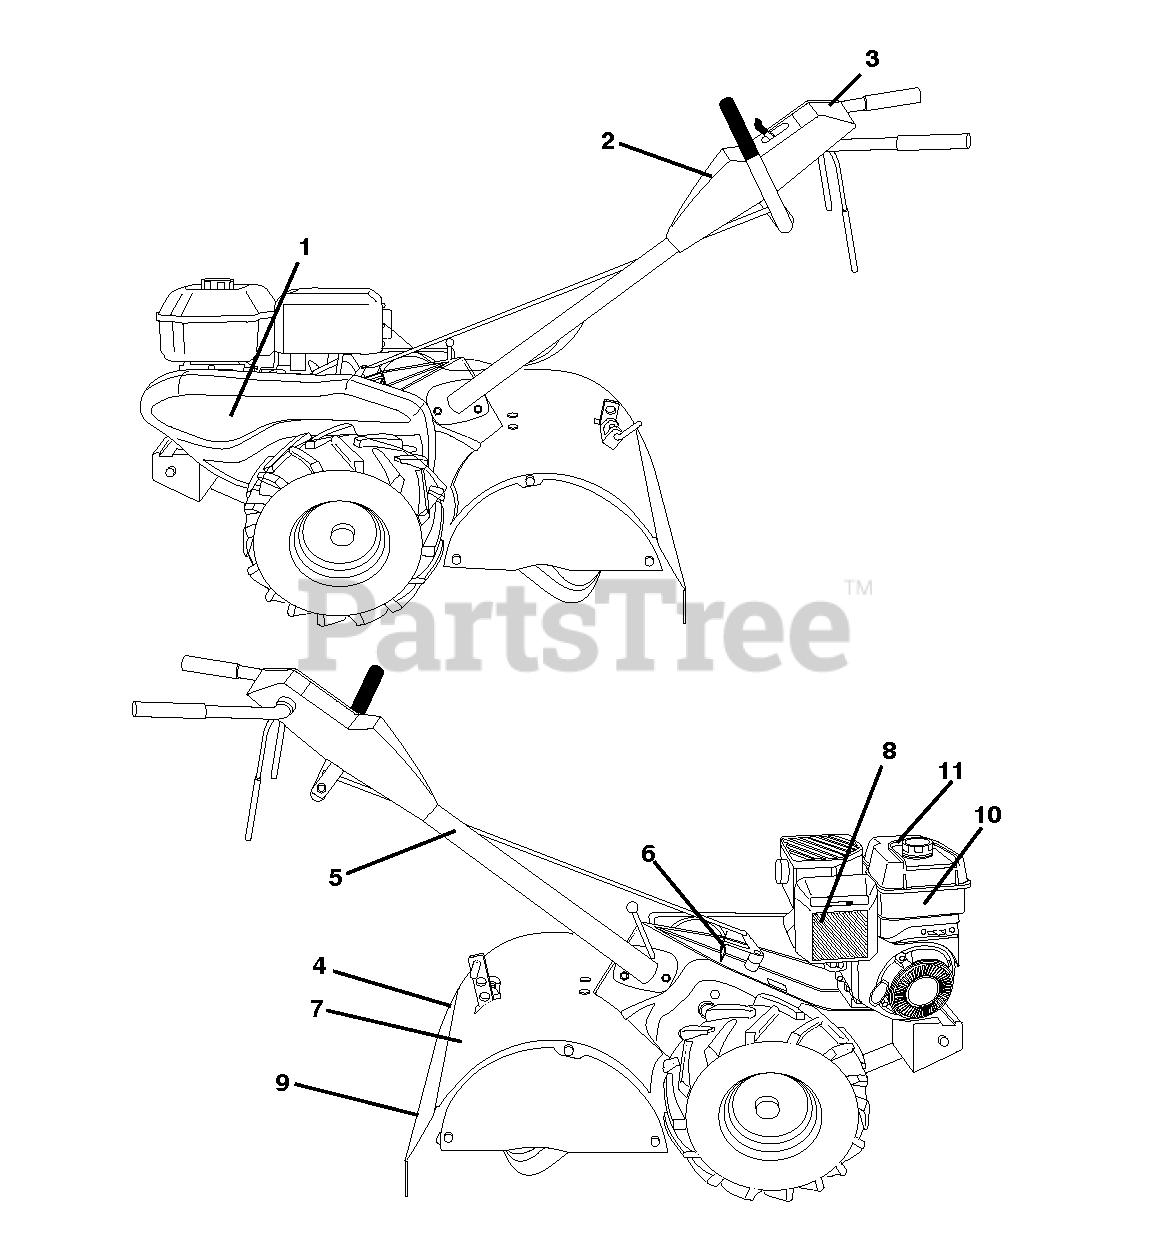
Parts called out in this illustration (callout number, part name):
1	RP.DECAL.BADGE.170MM.TEXTLOGO
2	DECAL, HUSQVARNA,CONTROL PANEL
4	DECAL.SHIELD
5	DECAL TI (2 2)
6	DECAL.SHIFT.INDICATOR.TILLER
7	DECAL.WARNING.SHLD.ENG/FR
8	DECAL.B&S.900.A/S.C (279005)
9	DECAL TI
10	DECAL.B&S.900.TANK.REF.276991
11	DECAL,ETHANOL E85 WARNING
